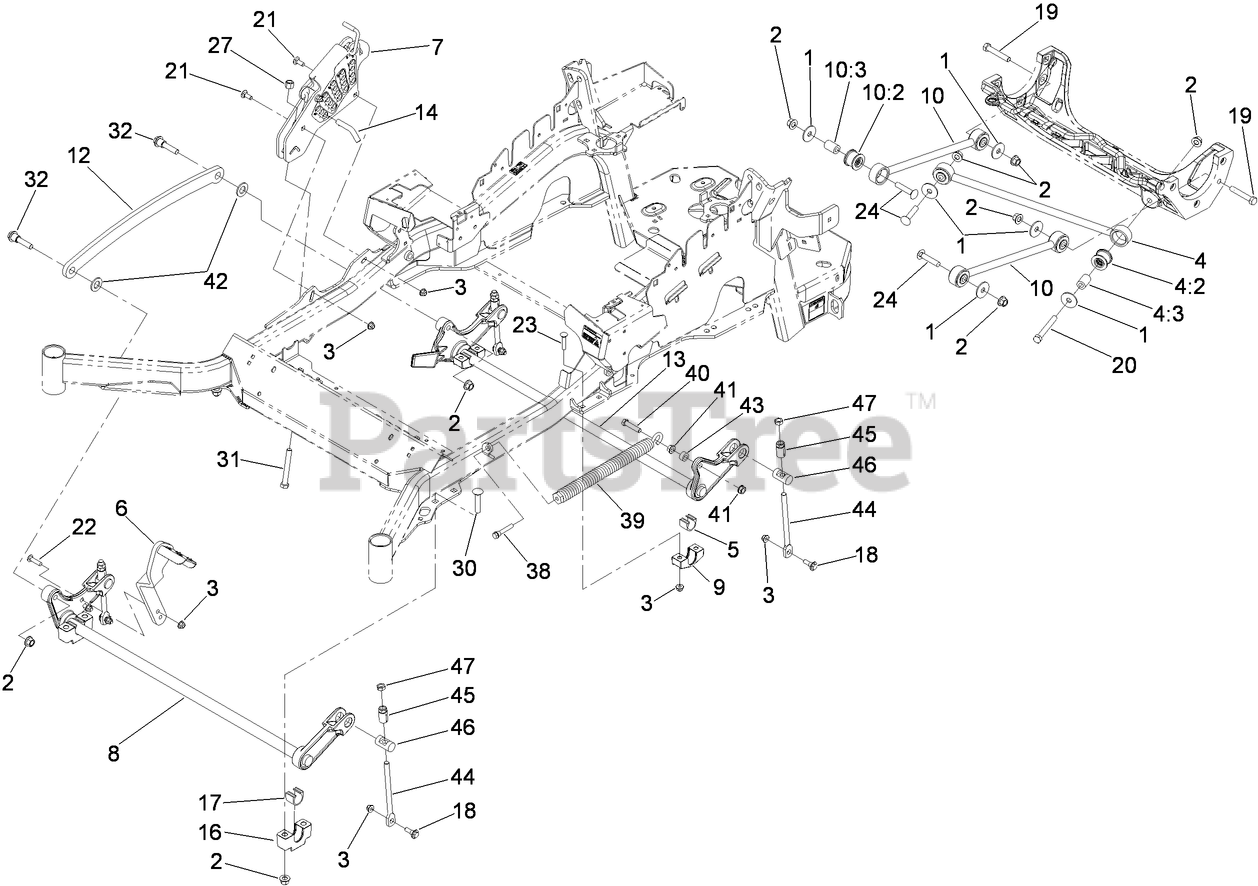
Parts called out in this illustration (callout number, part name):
1	WASHER-THRUST
2	NUT-LOCK
3	NUT-HF, NI
4	PANHARD ROD ASM
4:2	BUSHING-SUSPENSION, RUBBER
4:3	SPACER
5	BEARING-CROSS SHAFT, REAR
6	LEVER-FOOT
7	HOC ASM
8	DECK LIFT-FRONT
9	SUPPORT-CROSS SHAFT, REAR BEARING
10	DECK STRUT ASM
10:2	BUSHING-SUSPENSION, RUBBER
10:3	SPACER
12	LINK-LIFT, DECK
13	LIFT-DECK, REAR
14	PIN-HOC
16	SUPPORT-CROSS SHAFT, BEARING
17	BEARING-CROSS SHAFT, FRONT
18	SCREW-SHOULDER, HHF
19	SCREW-HH
20	SCREW-HH
21	BOLT-CARR
22	SCREW-CARR
23	SCREW-CARR
24	SCREW-CARR
27	NUT-LOCK, NI
30	SCREW-CARR, SHORT NECK
31	BOLT-TAP
32	SCREW-HHF, SHOULDER
38	BOLT-SHOULDER
39	SPRING-EXTENSION
40	SCREW-HH
41	NUT-HF
42	WASHER-FLAT
43	SPACER
44	LINK-ADJUSTER, DECK LIFT
45	ADJUSTER-LIFT, DECK
46	TRUNNION
47	NUT-JAM
